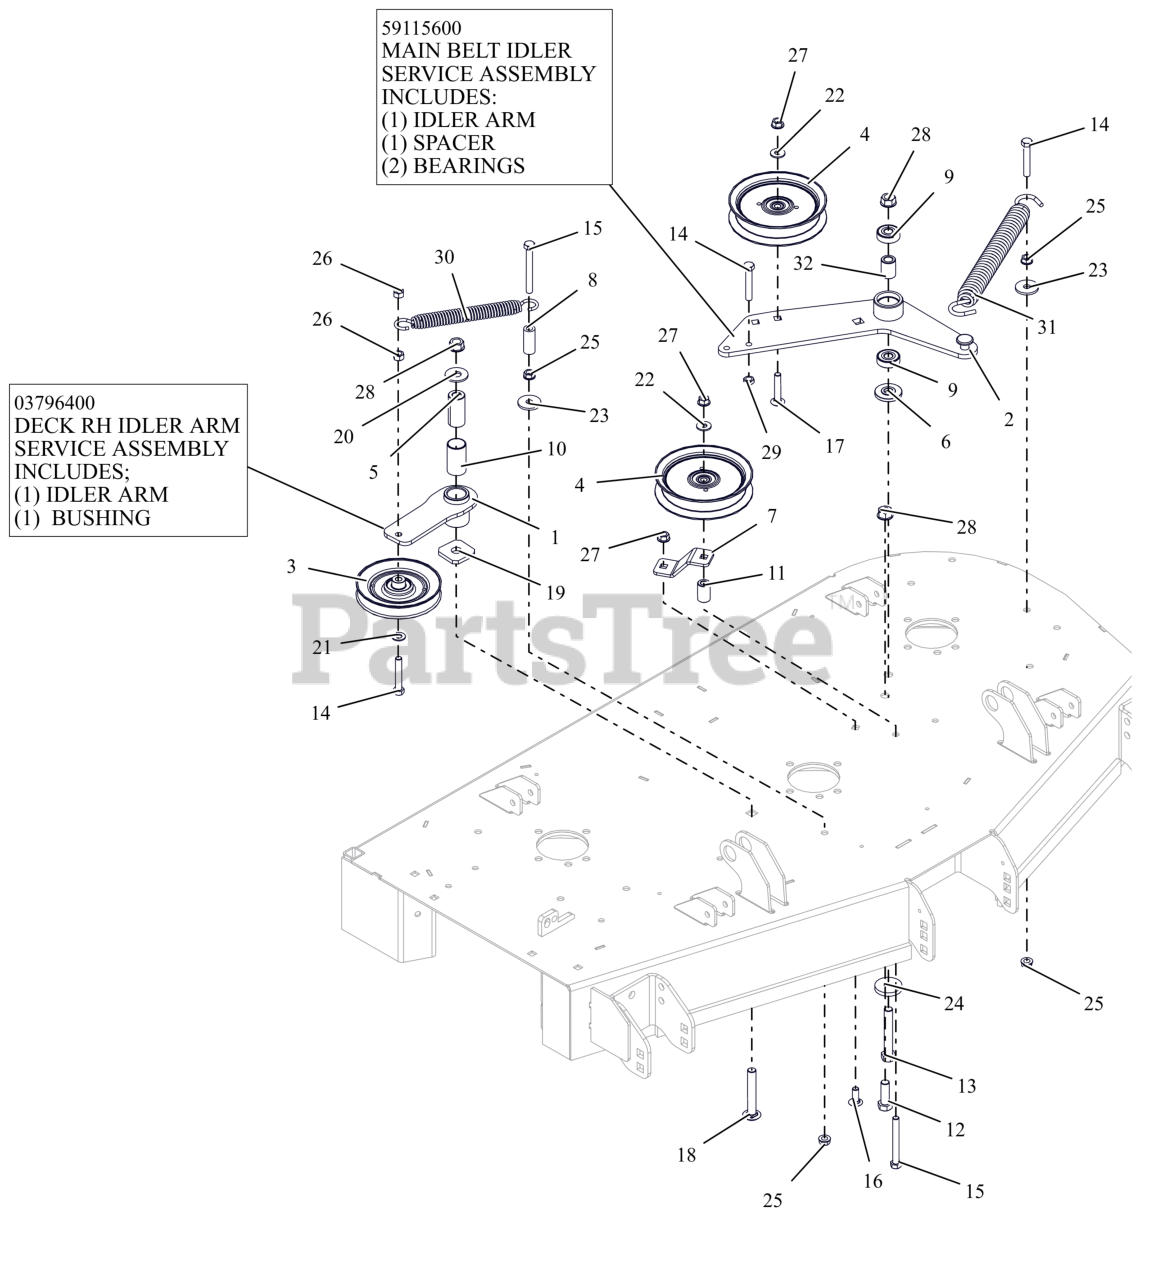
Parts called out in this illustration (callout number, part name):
1	WMT, IDLER ARM - BLACK
1	ASM, IDLER ARM (DECK)
2	WLDMT, DECK PTO IDLR ARM
2	ASSEMBLY, MAIN BELT IDLER
3	IDLER, V-5.00"
4	IDLER, FLAT 5.00"
5	BSHG, SPCR .502X.997X2.03 PM
6	SPACER, IDLER ARM
7	PTO FIXED IDLER MTG BRKT-ORG
8	HOSE, .38 X 1.65
9	BRG-BALL .500X1.38X.437
10	BSHG, 1.00X1.125X1.937
11	BUSHING, SLV .380X.750X1.190
12	BLT,HEX .50-13X1.50 G5 ZCC
13	BLT,HEX .50-13X3.25 G5 ZCC
14	BLT,HEX .38-16X2.25 G5 ZCC
15	BLT, HEX .38-16X3.25 G5 ZCC
16	BLT,RHSSN .38-16X1.00 G5 ZCC
17	BLT,RHSSN.375-16X2.00 G5 ZCC
18	BTL,RHSSN .500-13 X 3.25 G5 ZCC
19	WSHR-FLT .640X1.75X.250
20	WSHR,FLT .563X1.375X.109 ZCC
21	WSHR,FLT .406X.812X.065 ZCC
22	WSHR,FLT .375X.875X.083 ZCC
23	WSHR,FLT .406X1.375X.135 ZCC
24	WSHR-FL-STL .515X1.625X.250 YZ
25	NUT, SPNLK-FLG .38-16 G5 ZCC
26	NUT-LK-CTR .38-16 ZC120
27	NUT-LK-CTR-FLG .375-16 GF ZCC
28	NUT-LK-CTR-FLG .500-13 GG ZCC
29	NUT-JAM .375-16 G2 ZCC
30	SPRING, EXTENSION
31	SPRING, EXTENSION
32	SPACER .510 X .75 X 1.1485
